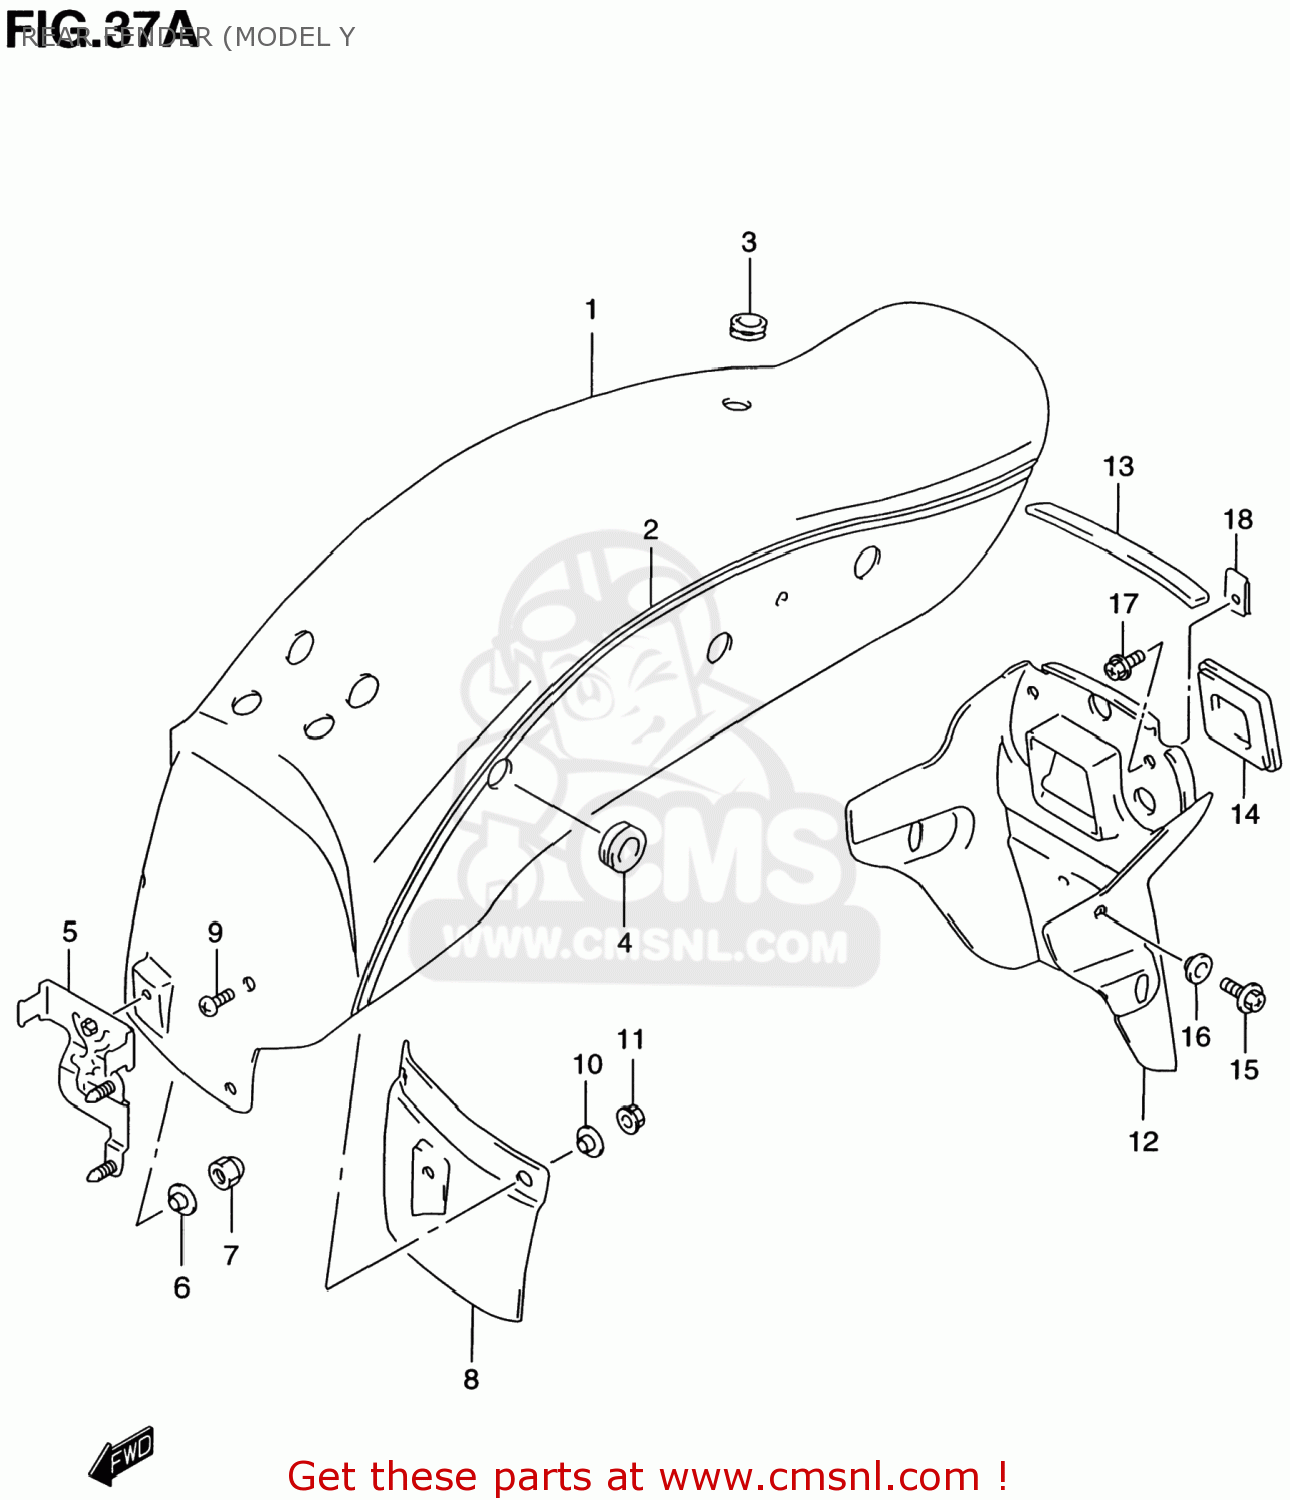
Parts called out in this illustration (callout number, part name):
1	FENDER COMP,REAR
2	TAPE SET,REAR FENDER
3	CUSHION
4	CUSHION,RR FENDER
5	BRACKET,RR FENDER
6	WASHER
7	NUT
8	MUDGUARD,RR FENDER
9	SCREW
10	WASHER
11	NUT
12	EXTENSION,RR FENDER
13	CUSHION,RR FENDER EXTENSION
14	CAP,RR FENDER EXTENSION
15	BOLT
16	WASHER
17	SCREW
18	PLATE,FRAME COVER
